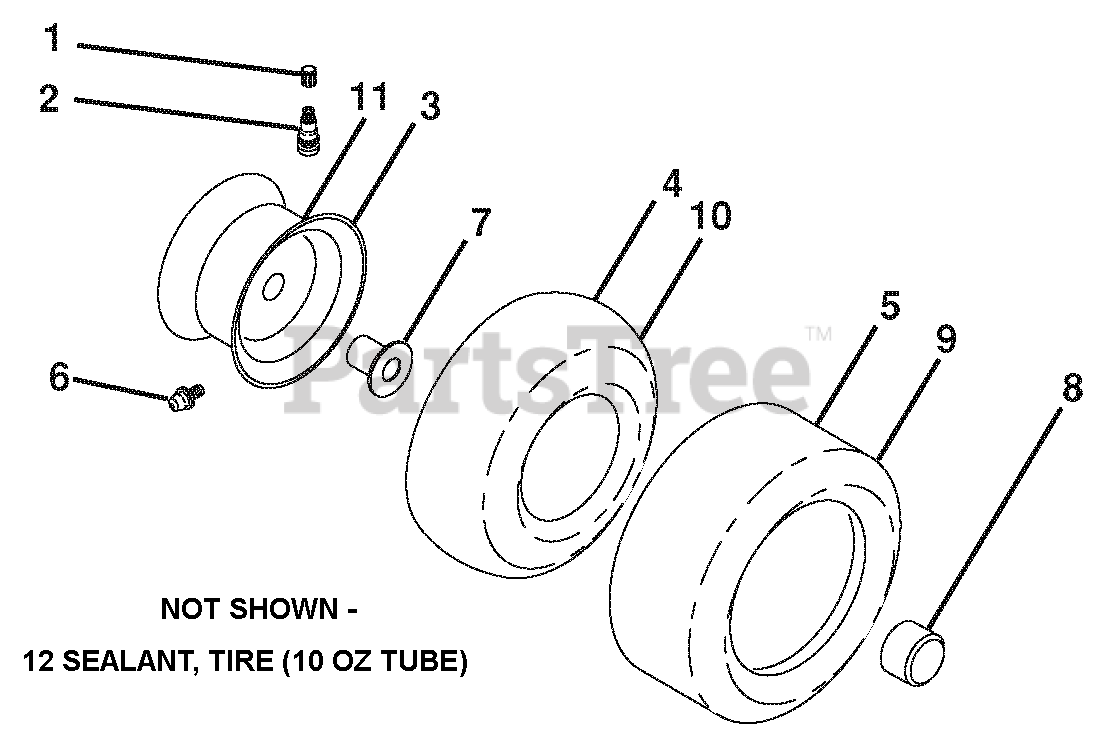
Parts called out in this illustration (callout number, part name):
1	CAP.VALVE.TIRE
2	STEM.VALVE
3	RIM ASM.6"FRONT.BLACK.SERVICE
4	TUBE.INNER.FRONT.#35060
5	TIRE.F.TS.15 X 6.0 - 6.SERVICE
6	FITTING.GREASE
7	BEARING.FLANGE
8	CAP.HUB.AXLE.W.GRY.1.50 X 1.00
9	TIRE.R.TS-LT.18X9.5-8.C.SERV.
10	TUBE.REAR.9.5 X 8.SERVICE
11	RIM ASM.8"REAR.W.GRY.SRVCE.643
